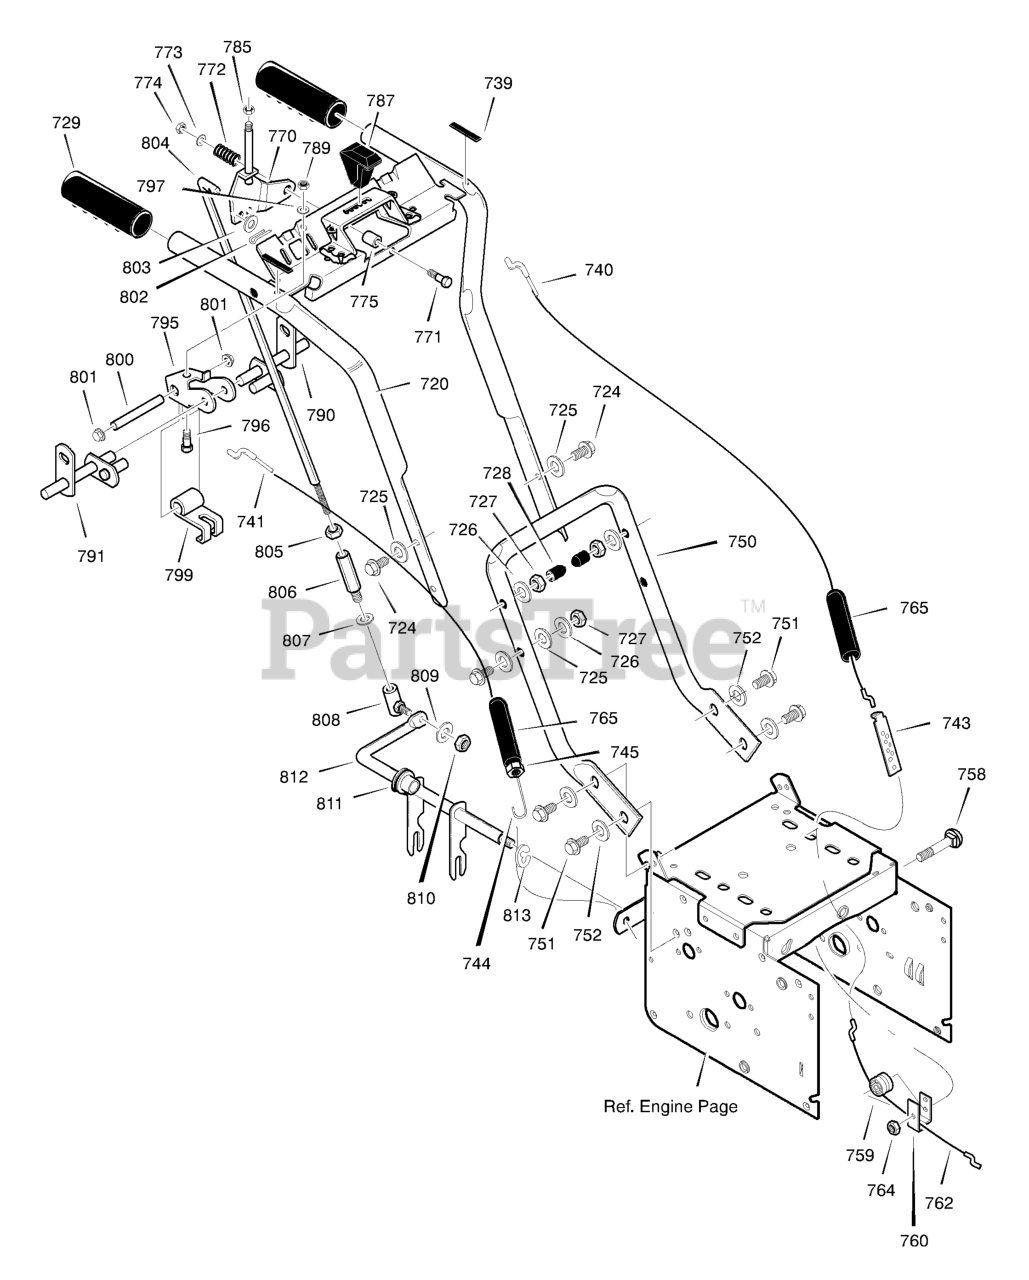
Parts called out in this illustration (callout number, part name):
720	ASSY, HANDLE -UPPER
723	SCREW
724	SCREW
725	WASHER, FLAT
726	WASHER
728	STOP, PLASTIC
729	GRIP, HANDLE
739	BUMPER
740	CABLE, CLUTCH
741	CABLE, CLUTCH
743	BRACKET, CABLE ADJUST
744	SPRING, CLUTCH
745	NUT, HEX
750	HANDLE, LOWER
751	SCREW
752	WASHER, SPTLK
754	SCREW
758	BOLT, HEX
759	SPOOL, CABLE
760	BRKT, SPOOL
762	CABLE, LOWER DRIVE
765	BOOT, CABLE
770	BRACKET, SHIFT
771	SCREW
773	WASHER, FLAT
774	NUT, HEX
775	SPACER, SHIFT
785	NUT, HEX
787	KNOB, SHIFT
790	ROD, ASSY LH
791	ROD, ASSY RH
795	BRACKET, CAM
797	WASHER, SPTLK
798	NUT, HEX
799	CAM LOCK
800	PIN, SPRING PIVOT
801	NUT, PUSH ON
802	PIN, COTTER
803	FLATWASHER
804	ROD, CONTROL
805	NUT, HEX
806	ADAPTOR, SPEED
807	WASHER
808	JOINT, STEEL BALL
809	WASHER
810	NUT, HEX
811	BEARING, FL
812	ROD, YOKE
813	RETAINER, RING
